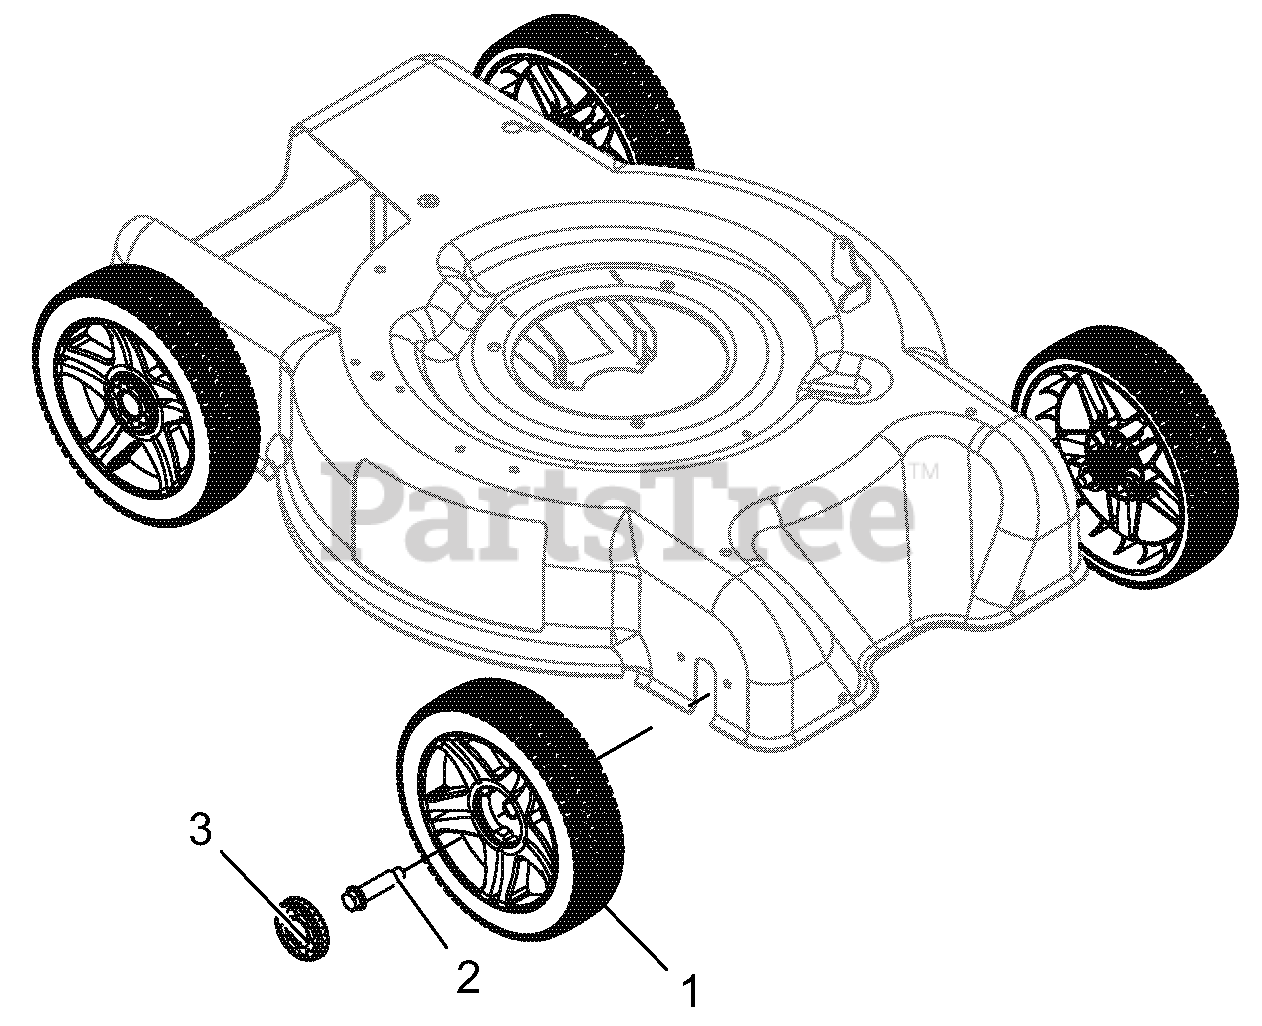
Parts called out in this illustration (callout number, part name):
1	WHEEL, LM - XD3
2	BOLT, SHLDR
3	CAP, LM WHEEL HUB - GRAVELY
